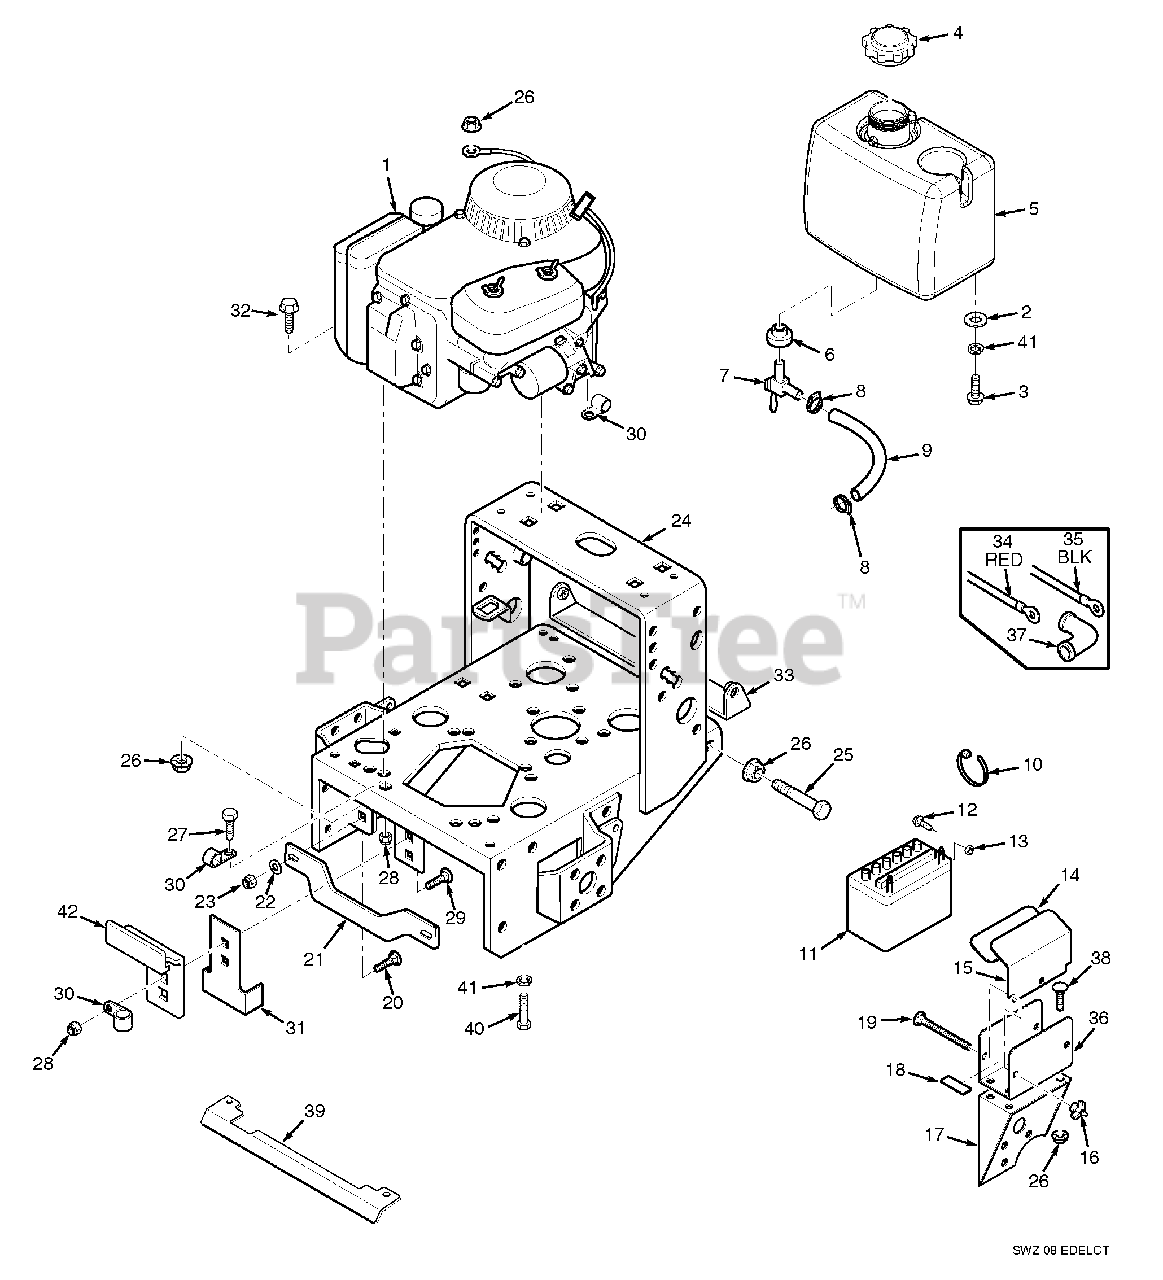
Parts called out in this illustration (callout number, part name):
1	Engine, 21KAE Kawasaki (Spec FH641V-GS06-R)
2	Flatwasher, 5/16-.375 x 875 x .083
3	Capscrew, 5/16-18 x 1" Hex Head
4	Cap, Fuel Tank
5	Fuel Tank Assy.
6	Bushing
7	Valve, Fuel Shut Off w/Screen
8	Clamp, Fuel Hose
9	Fuel Hose, 1/4 ID x 20"
10	Cable Tie
11	Battery
12	Bolt, 1/4-20 x 1/2"
13	Nut, 1/4-20
15	Battery Cover
16	Wing Nut, 1/4-20
17	Battery Support
18	Pad, Rubber
19	Bolt, 1/4-20 x 6" Carriage
20	Carriage Bolt, 3/8-16 X 1-1/4"
21	Brace, 20" Large Frame
22	Flat Washer .391 x .938 x .105
23	Nut, 3/8-16 Elastic Stop
24	Engine Deck, 20" Wide, w/decals
25	Bolt, 5/16-18 x 2" Hex Head
26	Nut, 5/16-18 Serr. Flange
27	Hex Head Bolt, 5/16-18 x .75"
28	Nut, 5/16-18 Elastic Stop
29	Carriage Bolt, 5/16-18 x 1"
31	Clutch Bracket
32	CapScrw, 5/16-18 x 1.50" Serrated Flg.
33	Pulley Guard, 20" Frame
34	Battery Cable, 31.5" Red
35	Battery Cable, 31.5" Black
36	Battery Box
37	Rubber Boot
38	Carriage Bolt, 5/16-18 x .75"
39	Heatshield, 20" Large Frame
40	Bolt, 5/16-18 x 1" Serrated Flg. Hex Head
41	Lock Washer 5/16"
42	Plate, Clutch Bracket
